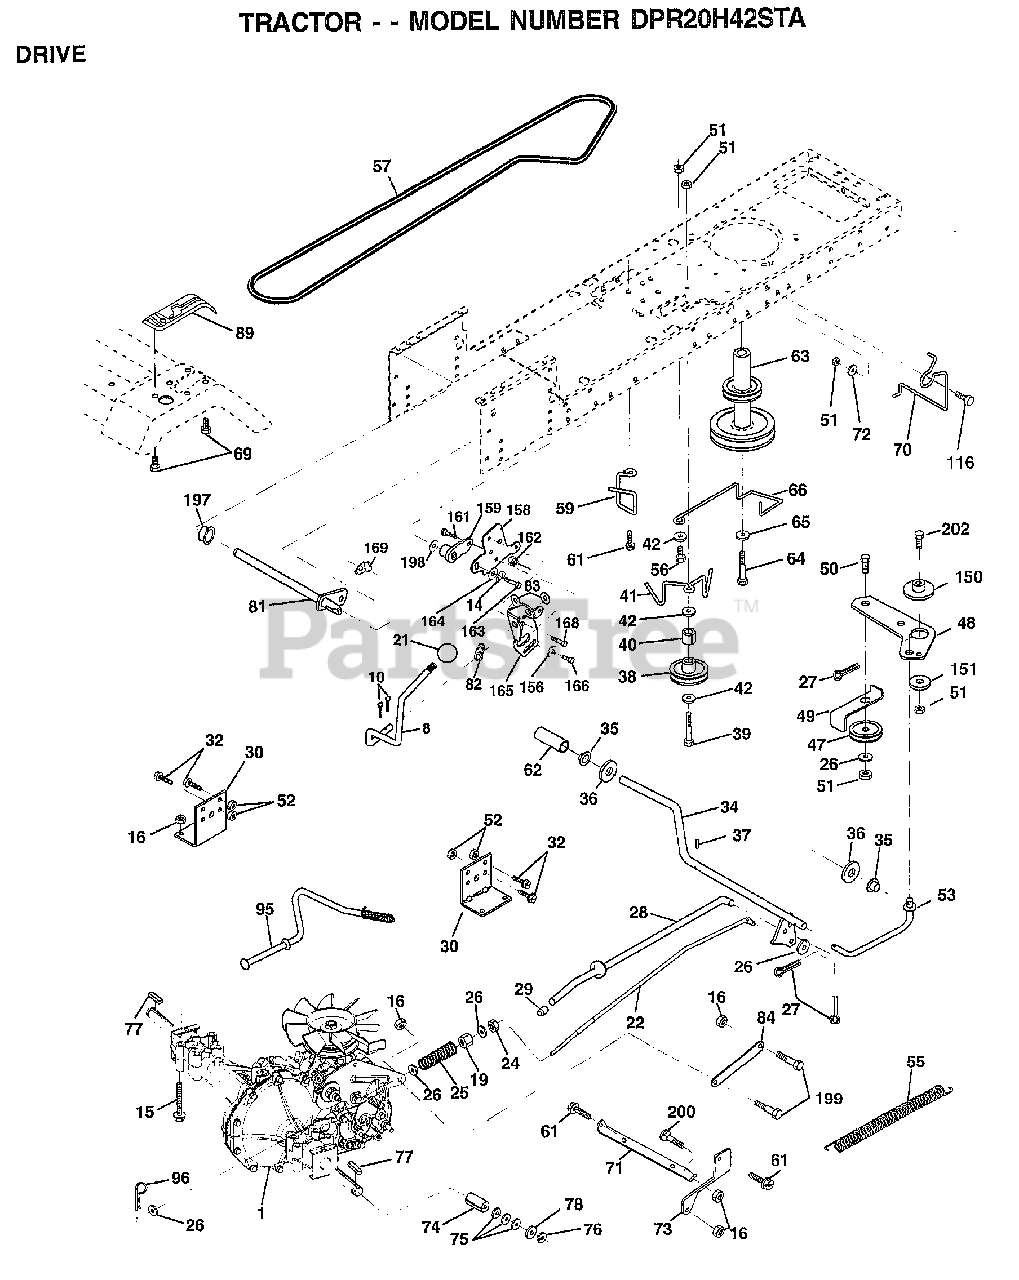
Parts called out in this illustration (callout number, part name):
8	ROD.SHIFT.FENDER.ADJ.LT.CRD
10	PIN COTTER 1/8
14	LOCKWASHER
15	BOLT.HX.FLG.5/16
16	NUT
19	NUT
21	KNOB DLX BLK/BLK
22	ROD BRAKE HYDRO
24	NUT
25	SPRING ROD LT
26	WASHER
27	COTTER PIN
28	ROD.BRAKE.PARK.LT
29	PLUNGER CAP T
30	BRACKET MTG TRANSAXLE
32	BOLT
34	SHAFT ASM-PEDAL F
35	NYLON BEARING
36	WASHER LT
38	FLAT IDLER PULLEY
39	BOLT
40	SPACER T
41	"KEEPER,BELT.IDLER FLAT"
42	WASHER
48	BELLCRANK.CLUTCH
49	RETAIN BELT
53	"LINK, CLUTCH T"
55	"SPRING, RETURN LT"
57	"BELT.GD DRV 82"""
59	KEEPER BELT SPAN CTR
61	SCREW
62	PEDAL COVER T
63	PULLEY.ENGINE
64	BOLT
65	LOCKWASHER
66	KEEPER-BELT
69	SCREW HEXWSH H-L
70	KEEPER BELT ENG
71	STRAP TORQUE LH HYDRO
72	WASHER
73	STRAP TORQUE RH HYDRO
74	SPACER
75	WASHER
76	E-RING LT
77	SQUARE KEY
78	WASHER
81	SHAFT
82	"SPRING,TORSION"
83	WASHER
84	LINK TRANSAXLE
89	CONSOLE HYDRO
95	CONTROL ASSY
96	RETAINER M
116	BOLT RDHD 3/8-16
150	BUSHING.BELLCRANK.GRD.DR
151	WASHER
156	WASHER.SRRTD.5/16
158	BRKT.SHIFT.MOUNT
159	HUB.SHIFT
161	BOLT T
164	WASHER.5/8X.281X10GA
165	BRKT.PIVOT.LEVER
166	SCREW.5/16-18X5/8
168	BOLT.SHOULDER.5/16-18X.561
169	PLATE.FASTENING
197	NYLINER SNAP-IN
198	WASHER NYLINER
199	BOLT SHOULDER
200	BOLT
202	BOLT.3/8-16X1.50
